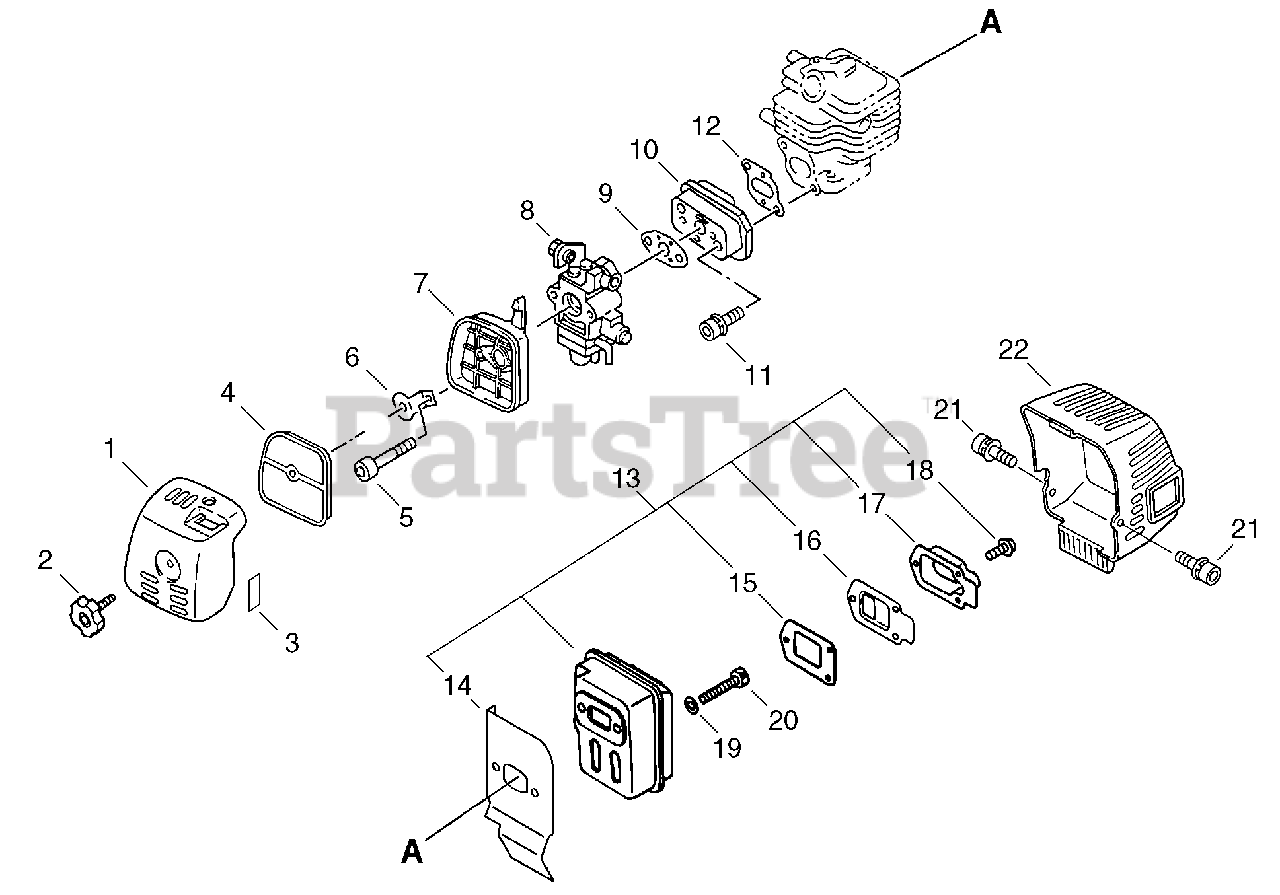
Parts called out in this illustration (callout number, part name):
1	COVER, AIR FILTER
2	THUMBSCREW
3	LABEL, CHOKE
4	FILTER, HEAVY-DUTY AIR
5	SCREW 5×55
6	PLATE, PREVENT
7	CASE, AIR FILTER
8	CARBURETOR - WYJ-192A
9	GASKET, CARBURETOR
10	INSULATOR, INTAKE
11	BOLT 5×25
12	GASKET, INTAKE
13	MUFFLER ASSY
14	HEAT SHIELD, EXHAUST
15	GASKET, EXHAUST
16	GUIDE, EXHAUST
17	OUTLET, EXHAUST
18	SCREW 4×10
19	WASHER, FLAT 5.5×10×0.8
20	BOLT 5×55
21	BOLT 5×12
22	COVER, MUFFLER
